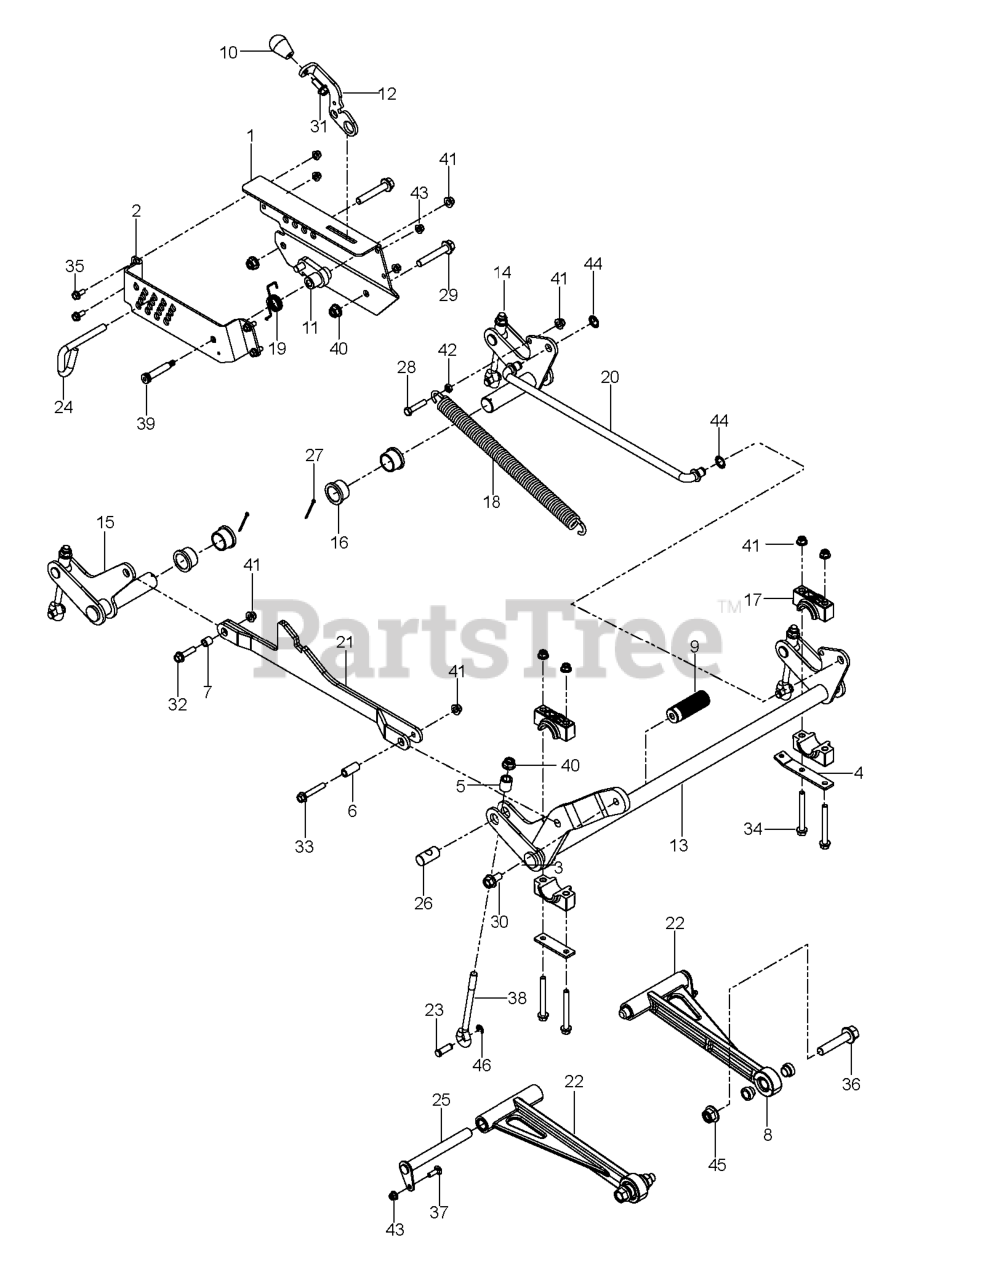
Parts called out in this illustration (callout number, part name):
1	PLATE, HEIGHT INNER ORG
2	PLATE, HEIGHT OUTER ORG
3	PLATE, PILLOW BLACK
4	PLATE, SPRING ANCHOR
5	SPACER, EYEBOLT
6	SPACER, FRONT LIFT STRAP
7	SPACER, REAR LIFT STRAP
8	SPACER, STRUT
9	PEDAL, DECK HEIGHT
10	KNOB - SHIFT
11	LATCH, TRANSPORT WLDMT
12	LEVER, TRANSPORT RELEASE
13	SHAFT DECK LIFT FT
14	SHAFT, LIFT LEFT REAR
15	SHAFT, LIFT RIGHT REAR
16	BUSHING, FLANGE 1.25 X 1.0
17	BLOCK, PILLOW
18	SPRING, EXTENSION
19	SPRING, TORSION
21	WELDMT, DECK STRAP
22	ASSEMBLY, STRUT
23	PIN, 7/16 CLEVIS
24	PIN, HEIGHT
25	PIN, STRUT
26	PIN, TRUNION, EYEBOLT
27	COTTER PIN 1/8 X 2
28	HCS 3/8-16 X 1 3/4 GR5
29	HFFS 1/2-13 X 3 GD 5 ZD
30	HHFS 1/2-13 X 1 GR5 ZD
31	HHFS 3/8-16 X 1 GRD 5 ZD
32	HHFS 3/8-16 X 1.50 GR5 ZD
33	HHFS 3/8-16 X 2-1/4 GR 5 ZD
34	HHFS 3/8-16 X 3.5 GD 5 ZD
35	HHFS 5/16-18 X 3/4
36	HHFS 5/8-11 X 3.0 GD 8 ZD
37	RHSNB 5/16C X 1
38	EYEBOLT, DECK LIFT
39	BOLT, SHOULDER, 1/2 X 2.25
40	NUT, 1/2-13 HEX FLG NYLOC ZD
41	NUT 3/8-16 HEX FLG NYLOC ZD
42	NUT 3/8-16 HEX JAM
43	5/16-18 NYLOC FLANGE NUT
44	NUT 5/8 PUSH
45	NUT 5/8-11 FLG NYLOC ZD
46	RING, E, 7/16
